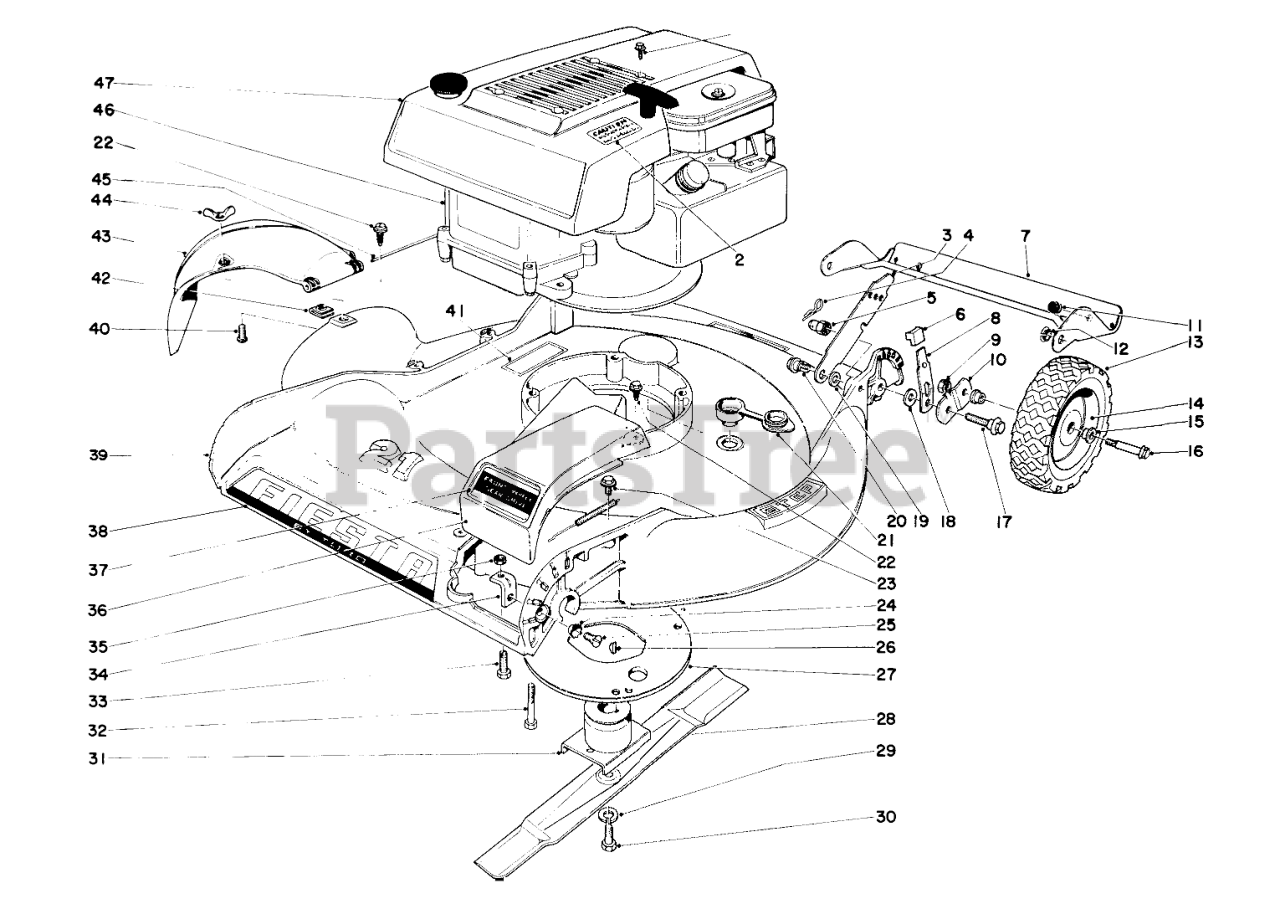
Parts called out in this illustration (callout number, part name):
1	8X1/2 SELF TAP SCREW
2	Decal-Warning
3	Latch
4	PIN-COTTER, HAIR
5	Nut
6	Arm Knob
7	Rear Safety Shield (Incl. #11)
8	Spring Arm
9	Nut
10	Pivot Arm
11	SKID BUTTON
12	Nyliner
14	Wheel (Incl. Ref. #15)
15	FLANGE BUSHING
16	Wheel Bolt
17	Pivot Screw
18	Pivot Washer
19	SPACER
20	SCREW-SHOULDER
21	WASHOUT PLUG
22	SCREW-HWHTF
23	Screw
24	Lockwasher
26	KEY-WOODRUFF
27	Grass Guard
28	21 ROTORY BLADE
29	WASHER-LOCK
30	SPECIAL SCREW
31	Blade Retainer
32	3/8-16 X 2-3/4 CAPSCR
33	SCREW
34	ADJ BRACKET
35	NUT-JAM
36	Cover, Belt Drive
37	Decal, Power Drive
38	Decal
39	Housing
41	Decal, Warning
42	NUT-SPEED
43	Deflector
44	NUT-WING SPECL
45	HINGE PIN
46	Engine
47	Shroud
